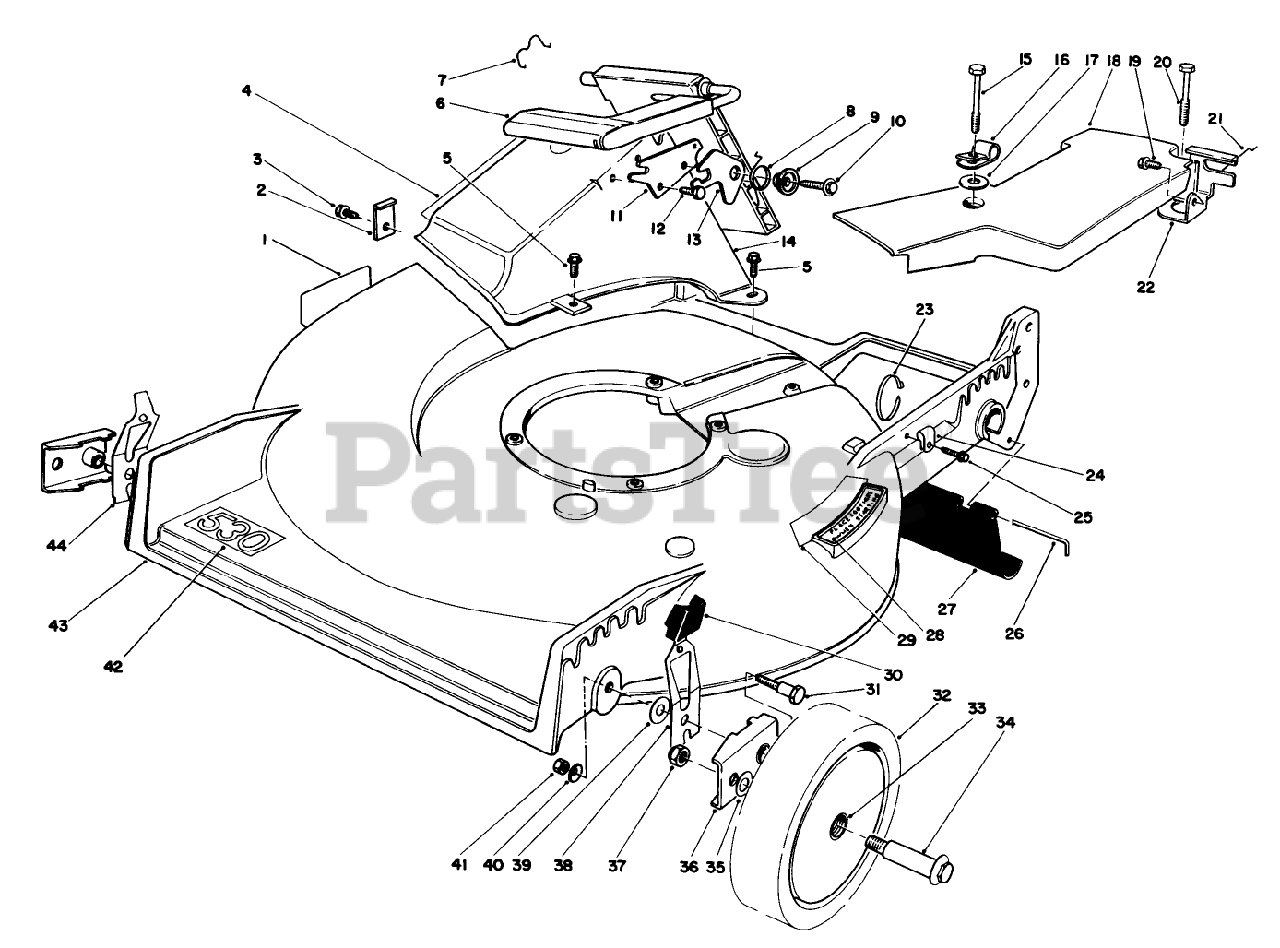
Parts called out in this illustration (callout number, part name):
1	DECAL-DANGER
2	TUNNEL CLIP
3	SCREW
5	SCREW-HWH
7	DOOR RET SPRING
8	TORSION SPRING
9	DOOR SPACER
10	SCREW-HWH
11	DOOR LATCH PLATE
12	SCREW-PLASTITE
13	SAFETY LATCH
15	SCREW-HWH
16	CLAMP-CABLE
17	WASHER
19	SCREW-THD ROLL, HWH
20	SCREW-SPECIAL
21	RETAINER-CABLE
23	TIE-CABLE
24	CLAMP-CABLE
25	SCREW
26	ROD-SHIELD
28	STEP PAD DECAL
30	KNOB-ARM
31	PIVOT SCREW
33	BUSHING
34	BOLT-WHEEL
35	WASHER
36	HP PIVOT ARM ASM
39	WASHER-PIVOT
40	WASHER-BELLEVILLE
41	NUT-LOCK, NI
